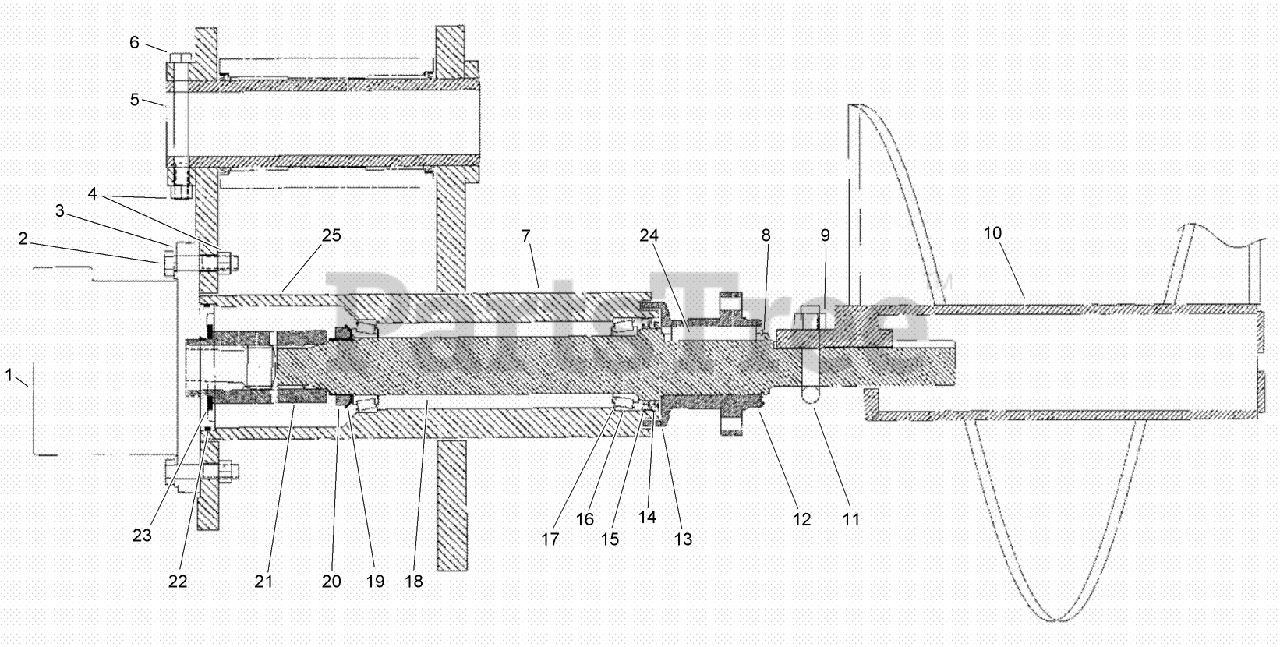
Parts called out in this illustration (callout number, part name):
1	MOTOR-Trencher
2	BOLT-Hex Hd 0.500 x 2.25 GR8 ZND
4	NUT-HEX
5	PIN-Pivot
6	BOLT-Hex Hd 1/2 x 4-3/4 GR8
7	HOUSING-Trencher Drive
8	RING-Retainer
9	NUT-LOCK, HEX
11	U-BOLT-Auger Retaining
12	HUB-Sprocket
13	SEAL-Urethane Excluder
14	HOUSING-Seal
15	SEAL-Oil
16	CUP-Bearing
17	CONE-Bearing
18	SHAFT-Trencher Drive
19	WASHER-Bearing Nut
20	NUT-Bearing
21	COUPLER-Trencher Drive
22	O-RING-Motor Seal
23	WASHER-Thrust
24	KEY-Chainline Drive, 1/2 x 3
25	PLUG-7/8-14 Cap
